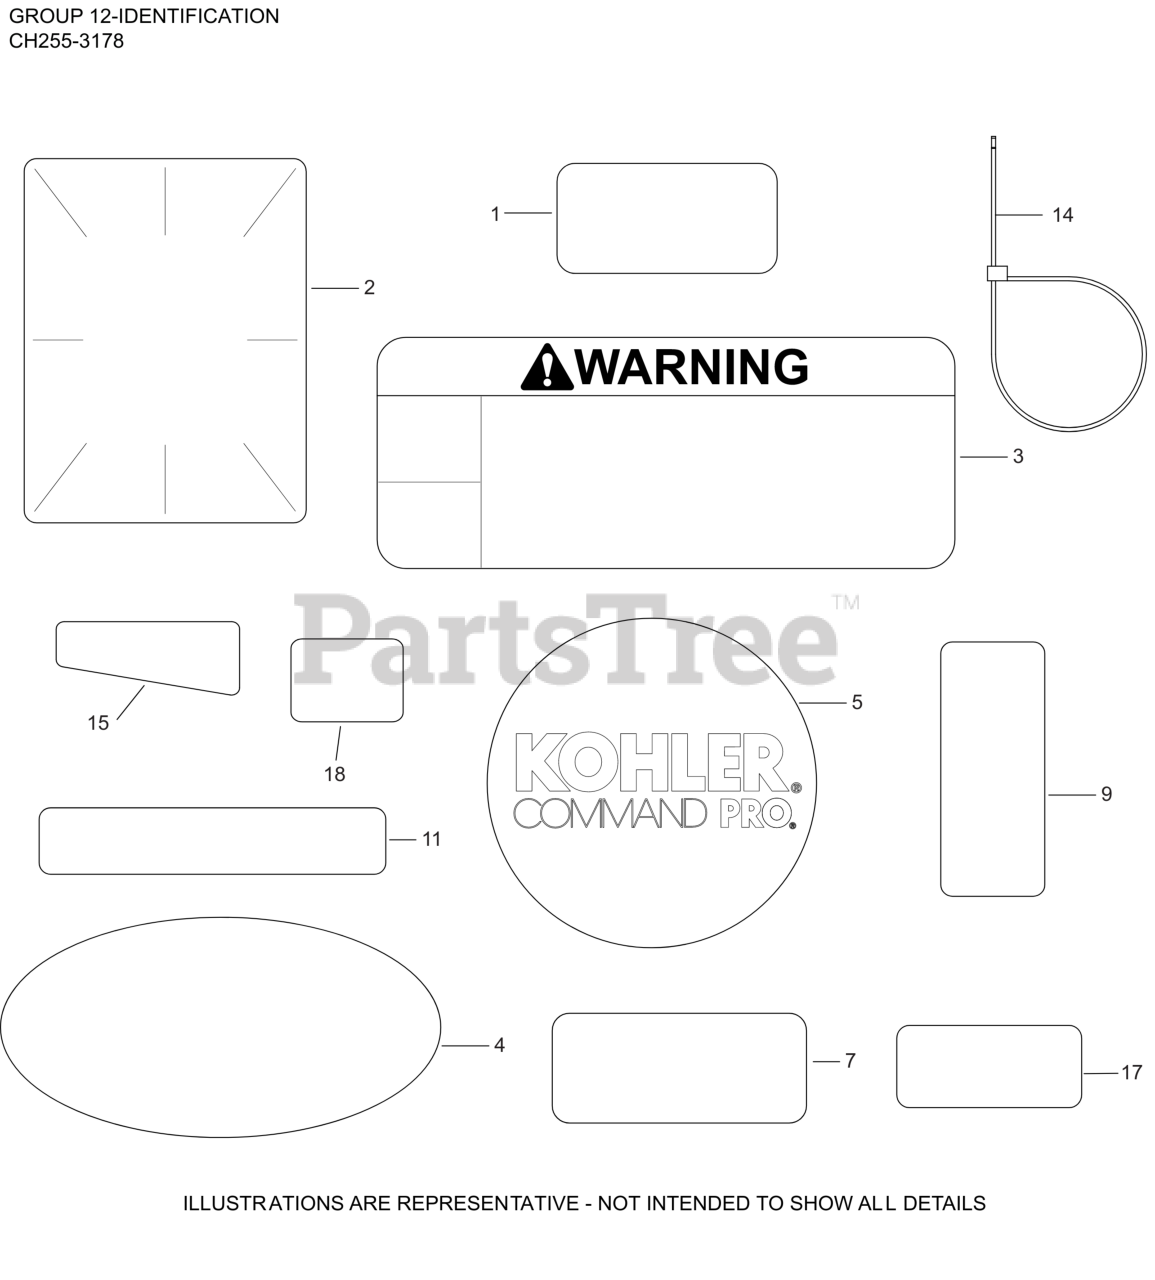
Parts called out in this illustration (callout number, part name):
1	LABEL, MAINTENANCE (CKY)
2	LABEL, CLEAR LAMINATION
3	DECAL, WARNING
4	DECAL, QUAD CLEAN
5	LABEL, RECOIL 75MM
7	LABEL, CANADIAN COMPLIANCE
9	DECAL, FUEL/CHOKE - ON/OFF
11	LABEL, THROTTLE
15	DECAL, 5.5HP/177CC CH255
17	DECAL, ETHANOL WARNING
18	DECAL, SUN
18	DECAL, SNOW
18	DECAL, ARROW
